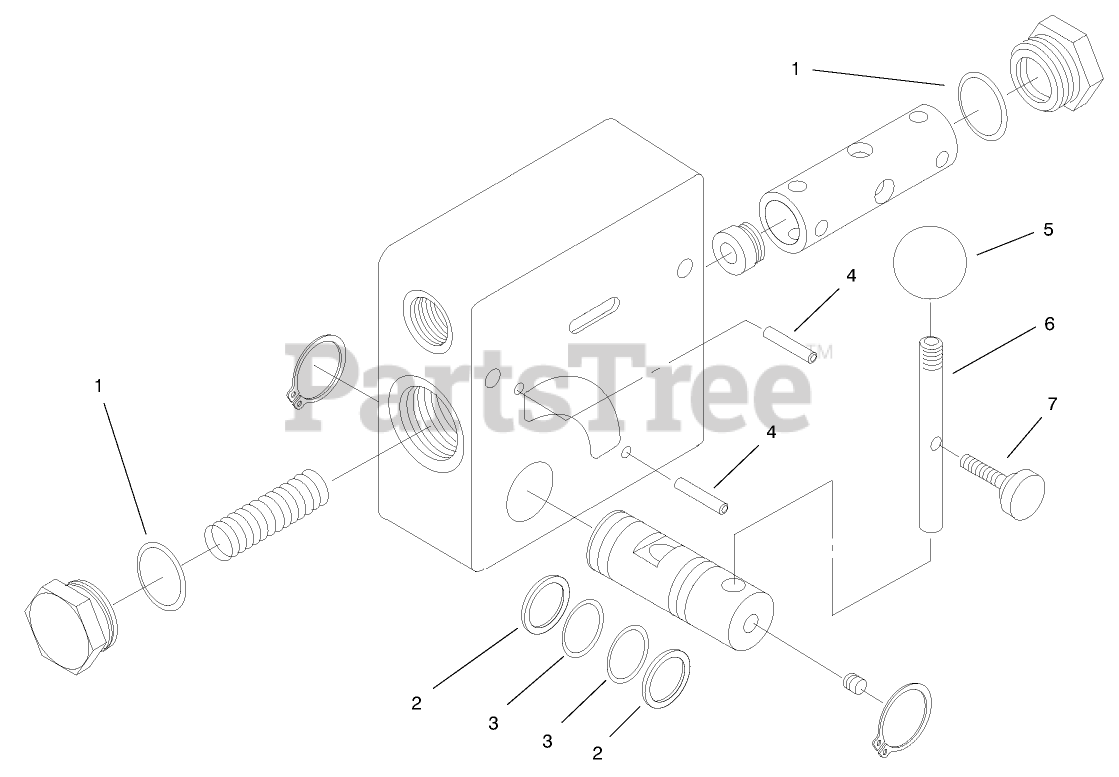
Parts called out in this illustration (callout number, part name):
2	Back-Up Washer
4	Roll Pin
5	Handle Knob
6	Handle
7	Thumb Screw
